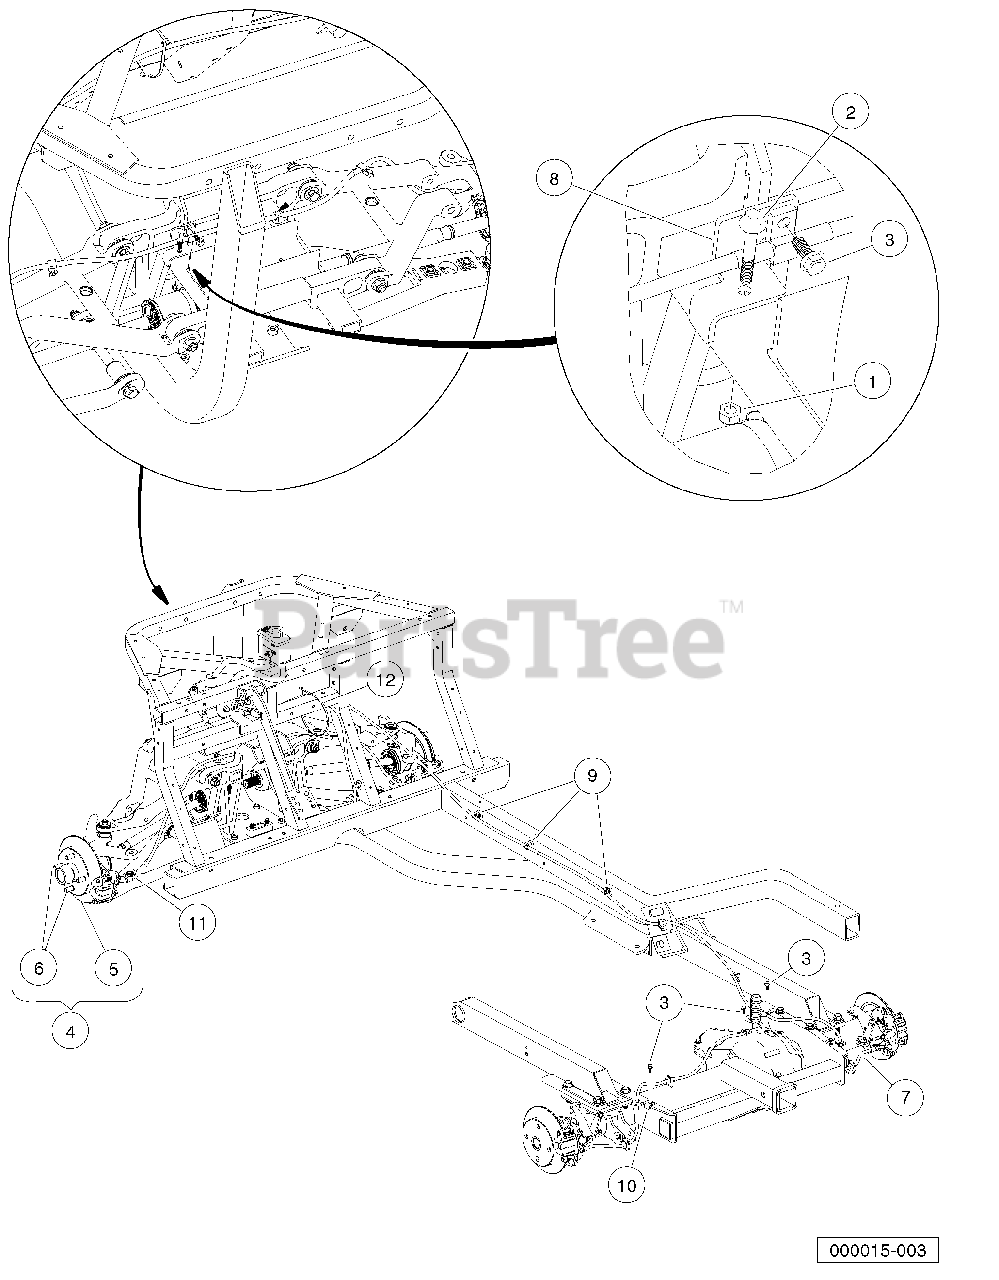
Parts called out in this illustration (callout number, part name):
1	Locknut, M6-1.00 Nylon Insert
2	Bolt, Flanged Head, M6x1.0x40
3	Screw, M6 X 16 Tt Hx Fl Hd
4	Assy, Rotor, Brake, Front, Wt
5	Rotor, Brake, Front, Wt
6	Stud, Wheel Lug
7	Assembly, Brake Line, Rear
8	Bracket, Tee, Brakeline
9	Clip, Brake Line
10	Bracket, Line, Hydraulic
11	Brakeline, Front, Assembly
12	Tie Wrap, 11" Nylon
